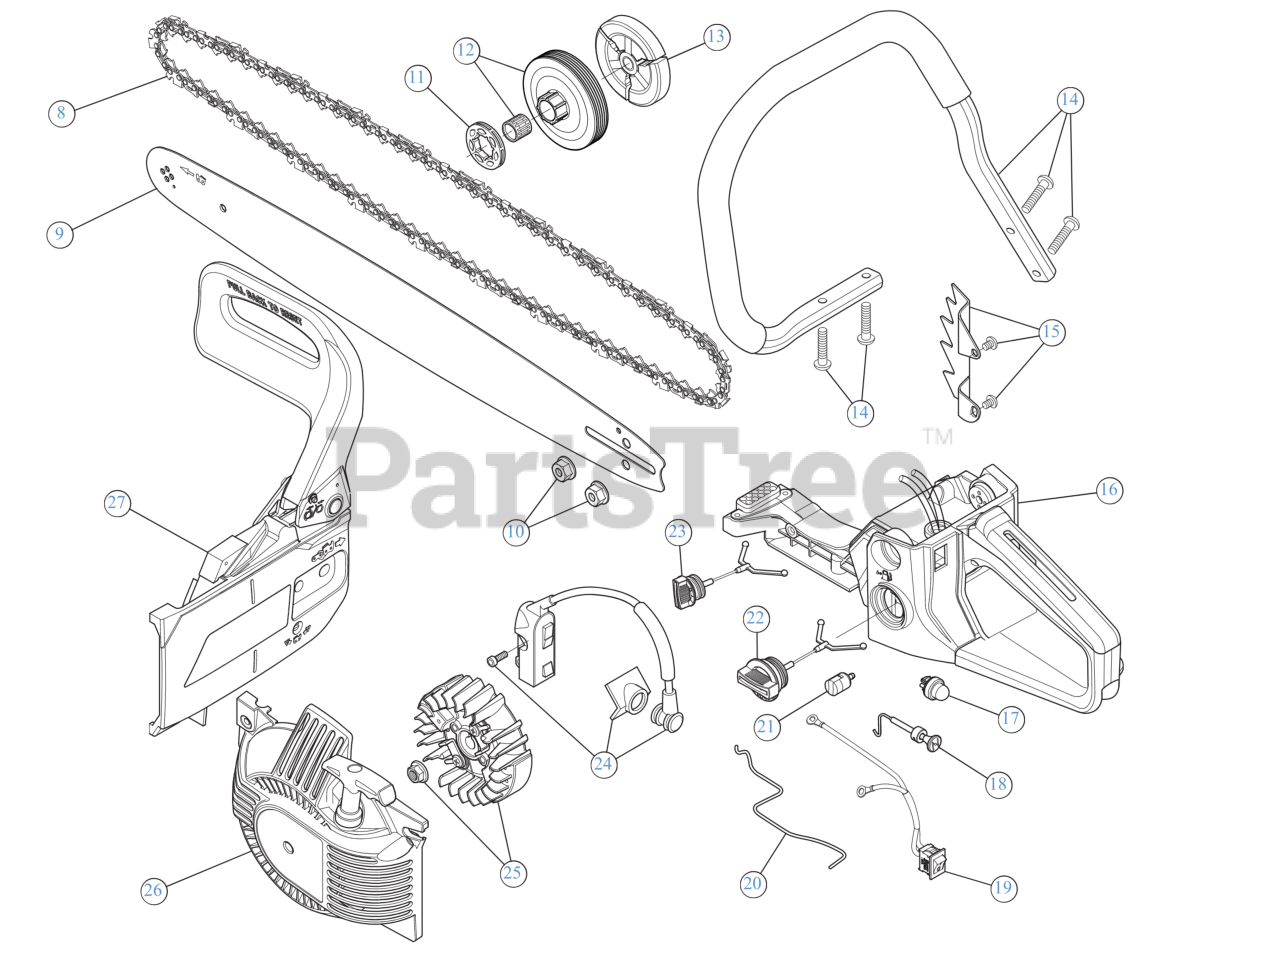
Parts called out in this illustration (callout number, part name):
8	CHAIN:14" TRILINK
8	CHAIN: 16" TRILINK
8	CHAIN 18" TRILINK
9	BAR: 14" TRILINK
9	BAR: 16" TRILINK
9	BAR 18" TRILINK
10	BAR NUT M8
11	SPROCKET
12	CLUTCH DRUM ASSEMBLY
13	CLUTCH ASSEMBLY
14	HANDLE ASSEMBLY
15	SPIKE PLATE W/HDW
16	FUEL HOUSING ASSEMBLY
17	PRIMER BULB YD2500-18410
18	CHOKE LEVER ASSEMBLY
19	SWITCH ASSEMBLY
20	THROTTLE ROD
21	FUEL FILTER YD4600-18034
22	FUEL CAP ASSEMBLY
23	OIL CAP ASSEMBLY
24	MODULE
25	FLYWHEEL
26	STARTER HOUSING ASSEMBLY
27	BRAKE ASSEMBLY:CHAINSAW
